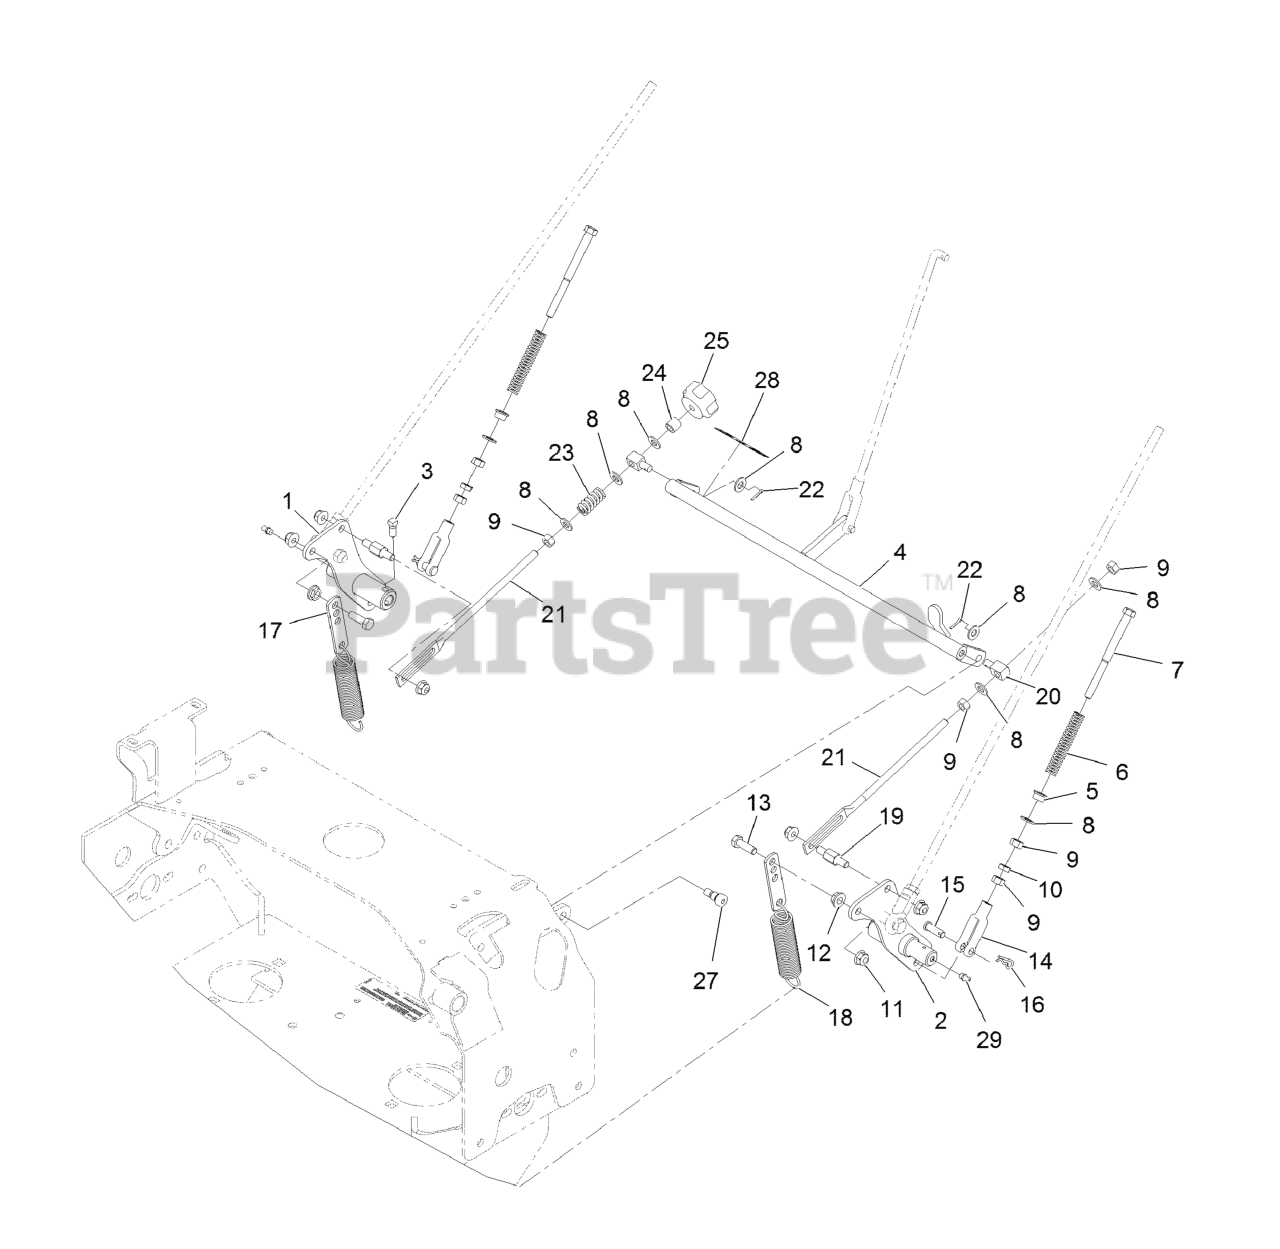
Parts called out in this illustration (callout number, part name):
1	WELD, MOTION CONTROL, RT
2	WELD, MOTION CONTROL, LT
3	SCREW-SET
4	WELD, SPEED CONTROL
5	BUSHING-FLANGED
6	SPRING,COMPRESSION (NEUT)
7	BOLT-RETURN, NEUTRAL
8	WASHER-PLAIN
9	NUT-HEX
10	NUT-JAM
11	NUT-HF, NI
13	SCREW-HH
14	YOKE-ADJUSTABLE
15	PIN-CLEVIS
16	PIN-COTTER
17	TAB-SPRING, EXTENSION
18	SPRING-EXTENSION
19	PIN, MOTION CONTROL
20	SWIVEL-ADJUSTABLE, SHORT
21	LINK-CONTROL, SPEED
22	PIN-COTTER
23	SPRING-COMPRESSION
25	KNOB-TRACKING
27	SCREW-HSH
28	DECAL-TRACKING ADJUSTMENT
29	FITTING-GREASE
